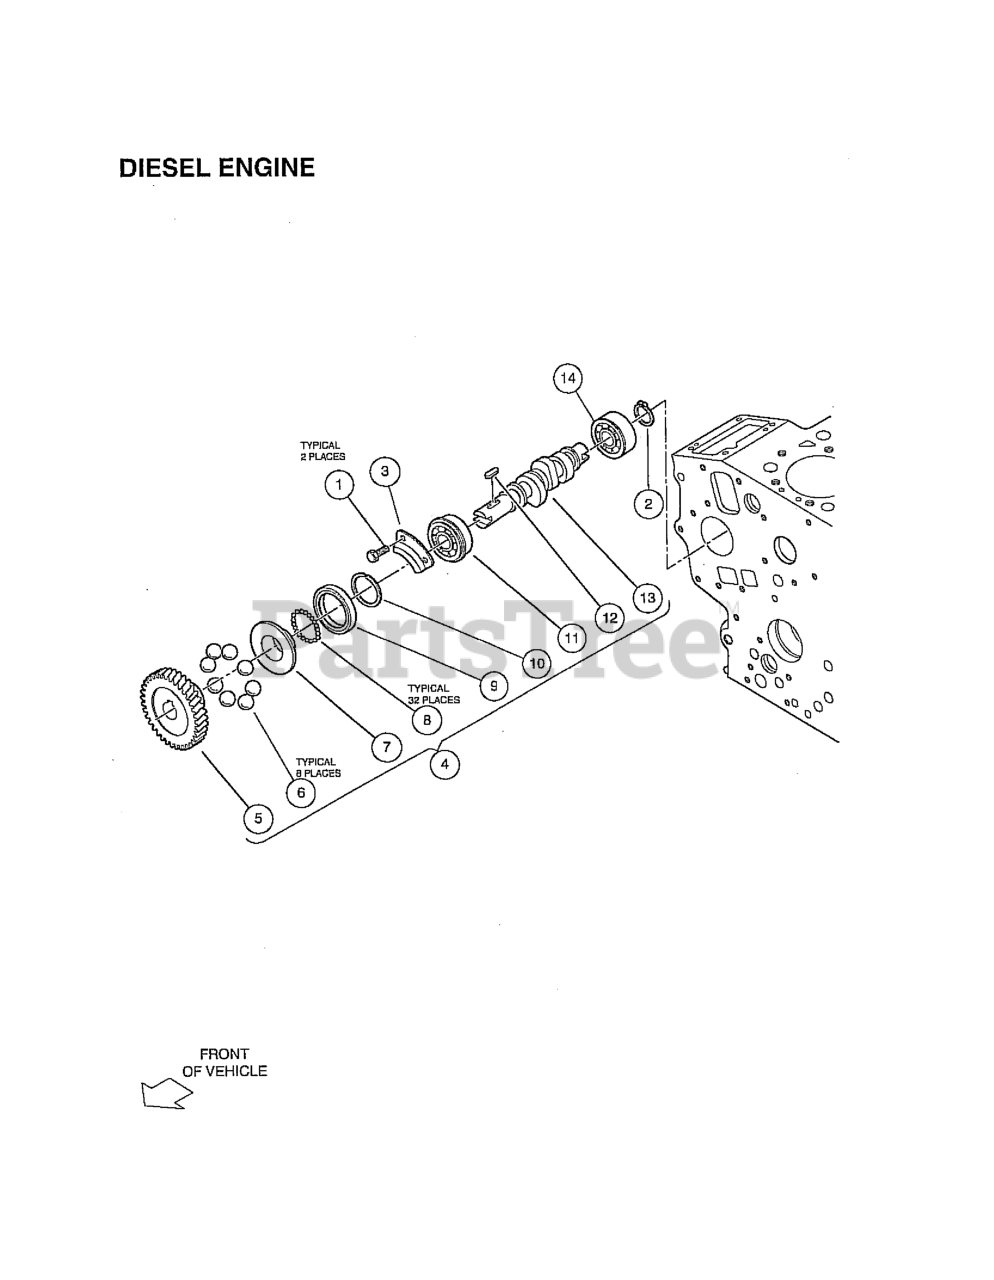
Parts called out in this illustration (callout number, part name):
1	BOLT, D722, CAM END
2	CIRCLIP, EXTERNAL
3	STOPPER, FUEL, C/SHAFT
4	ASSY, FUEL CAMSHAFT
5	GEAR, INJECTION PUMP
6	BALL, INJECTION PUMP
7	SLEEVE, GOVERNOR
8	BALL, GOVERNOR
9	CASE, GOVERNOR BALL
10	CIR-CLIP, GOV. SLEEVE
11	BEARING, BALL, LEFT
12	KEY, FEATHER, SHORT CAMSHAFT
13	CAMSHAFT, FUEL, SHORT
14	BEARING, BALL, FUEL CAM REAR
